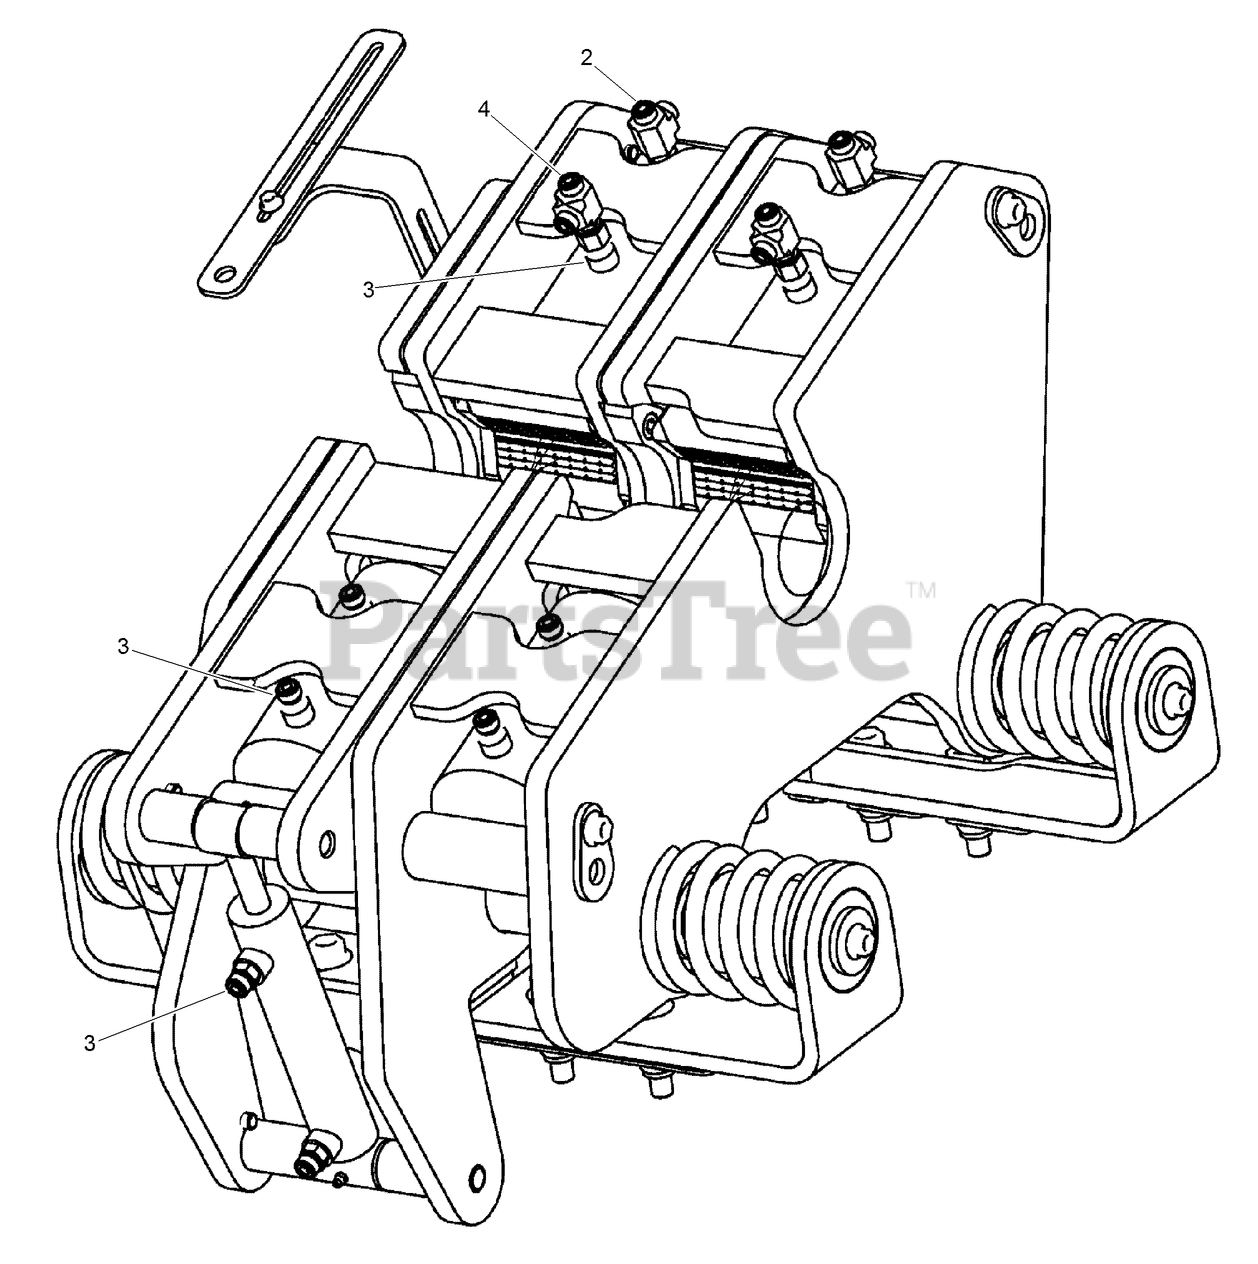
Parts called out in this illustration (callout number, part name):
2	CONNECTION - Run Tee, Orifice, 0.125 Dia
3	CONNECTION - Straight, -6 ORFS / -6 ORB
4	CONNECTION - Run Tee, -6 ORFS / -6 ORFS
